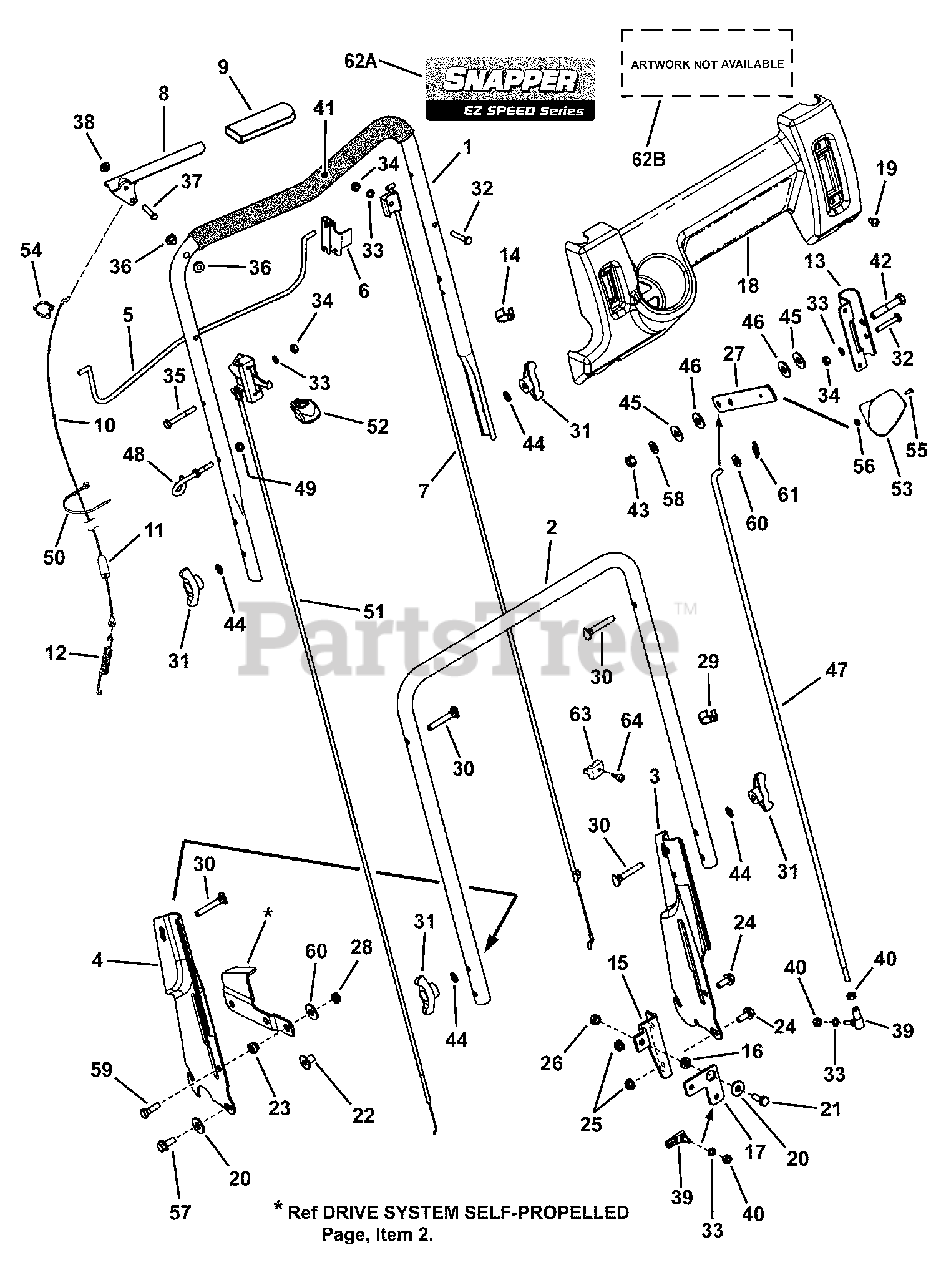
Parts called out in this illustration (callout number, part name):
1	HANDLE, Upper
2	HANDLE, Middle
3	HANDLE, Lower LH (Adjustable)
4	HANDLE, Lower RH (Adjustable)
5	BAIL, OPC Control
6	CLIP, Zone Control
7	* CABLE, Zone Control (52-63/64" Long)
7	* CABLE, Zone Control (52-21/32" Long)
8	HANDLE, Clutch
9	GRIP, International Symbol
10	CABLE, Clutch Control (41-1/4" Long)
11	COVER, Vinyl
12	SPRING, Clutch - 21S
13	BRACKET, Shift
14	TIE, Wire, 1.29 long, black
15	BRACKET, Bell Crank
16	SPACER, .33 x .63 x .156
17	BELL CRANK
18	CONTROL PANEL (w/o Electrical Switch Hole)
18	CONTROL PANEL (w/o wheel drive slot)
19	SCREW, 1/4-20 x .550" Pan Head Self-Tap (Torx)
20	WASHER, .33 x .88 x .09 Flat
21	SCREW, 5/16-18 x 7/8" Hex Head Cap, GR 5
22	TEENUT, 5/16-18
23	BUSHING, Differential, .328 x .625 x .41
24	BOLT, 5/16-18 x 3/4" Hex Flange Lock GR 5
25	NUT, 5/16-18 Hex Flange Lock, GR 5
26	NUT, 5/16-18 Hex Center Lock
27	LEVER, Shift
28	NUT, 5/16-24 Hex Center Lock GR 5
29	CLIP, Wiring Harness
30	SCREW, 5/16-18 x 1-7/8" Curved Head GR 2
31	KNOB, 5/16-18 Wing (Black)
32	SCREW, 1/4-20 x 1-1/2" Hex Head Cap GR 5
33	WASHER, 1/4" Internal Tooth Lock
34	NUT, 1/4-20 Hex
35	SCREW, 1/4-20 x 2" Hex Head Cap, GR 5
36	BUSHING, .27 x .35 x .4 Flange
37	PIN, 1/4 x 1-1/2"
38	PUSH-NUT, 1/4"
39	BALL JOINT, 1/4-28
40	NUT, 1/4-28 Hex
41	FOAM GRIP, 18.75" long
42	SCREW, 3/8-16 x 2" Hex Head Cap, GR 5
43	NUT, 3/8-16 Hex Center Lock
44	WASHER, 5/16" Internal Tooth Lock
45	WASHER, 7/16" Flat
46	WASHER, Nylon
47	ROD, Speed Control (1/4-28 thread)
48	GUIDE, Rope (1/4-20 thread)
49	NUT, 1/4-28 Hex GR 5 or B
50	CABLE-TIE, 7"
51	THROTTLE CONTROL, (48.5")
51	THROTTLE CONTROL, RP, D.O.V. Engine (50.0")
51	THROTTLE CONTROL, (62.0")
52	THROTTLE KNOB (Red)
53	KNOB, Shift (Red)
54	CLAMP, 7/8" Double Cable
55	SCREW, #8-32 x 1/2" Cross Recess Filister Head Machine
56	NUT, #8-32 Hex
57	SCREW, 5/16-18 x 1-1/4" Hex Washer Head Self-Tap
58	WASHER, Belleville
59	SCREW, 5/16-24 x 1" Hex Head Cap GR 5
60	WASHER, 11/32" Flat
61	COTTER PIN, 5/16 Self Lock
62A	DECAL, Easy Speed, Control Panel
62B	DECAL, Snapper Control Panel
63	CLAMP, Casing
64	SCREW, #10-32 x .62" Hex Head Self-Tap
